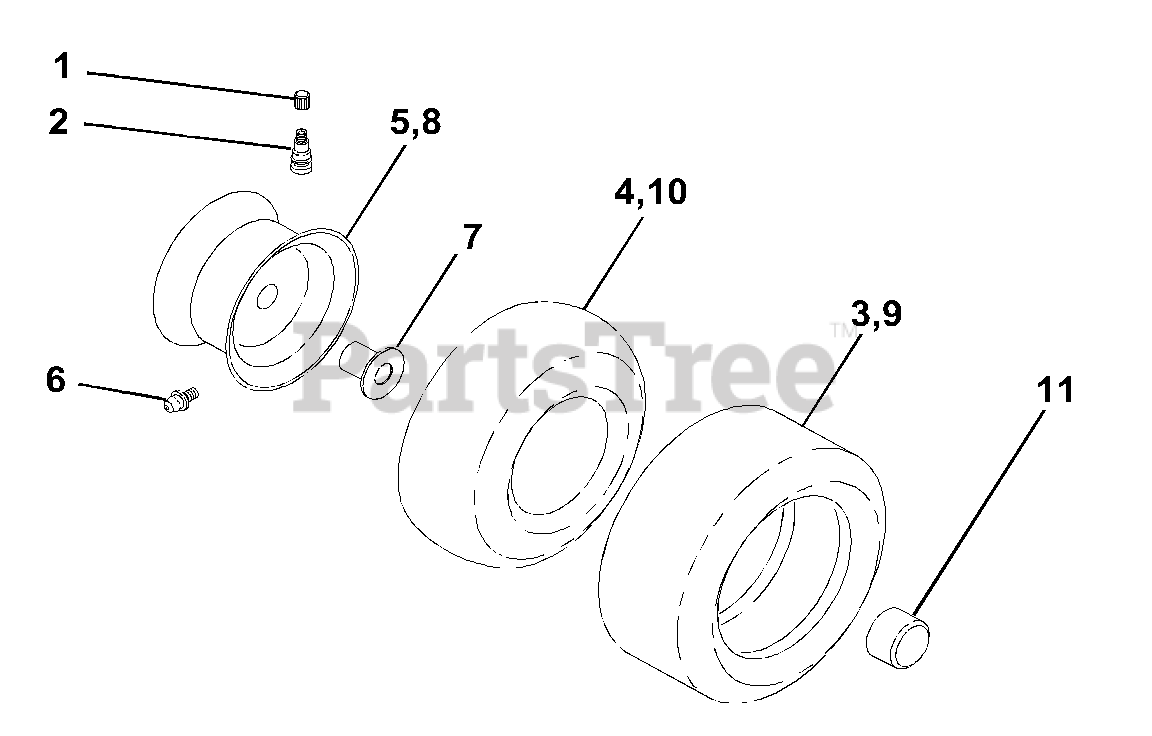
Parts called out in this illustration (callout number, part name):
1	Cap Valve Tire
2	Stem Valve
3	Tire F Ts 15 X 6 0 - 6 Service
4	Tube Front
5	Rim Asm 6" front Silver Service
6	Fitting Grease (Front Wheel Only)
7	Bearing Flange (Front Wheel Only)
8	Rim Asm 8" rear Silver Service
9	Tire R Ts 20x10-8 C Service
10	Tube Rear
11	Cap Axle Blk 1 50 X 1 00
